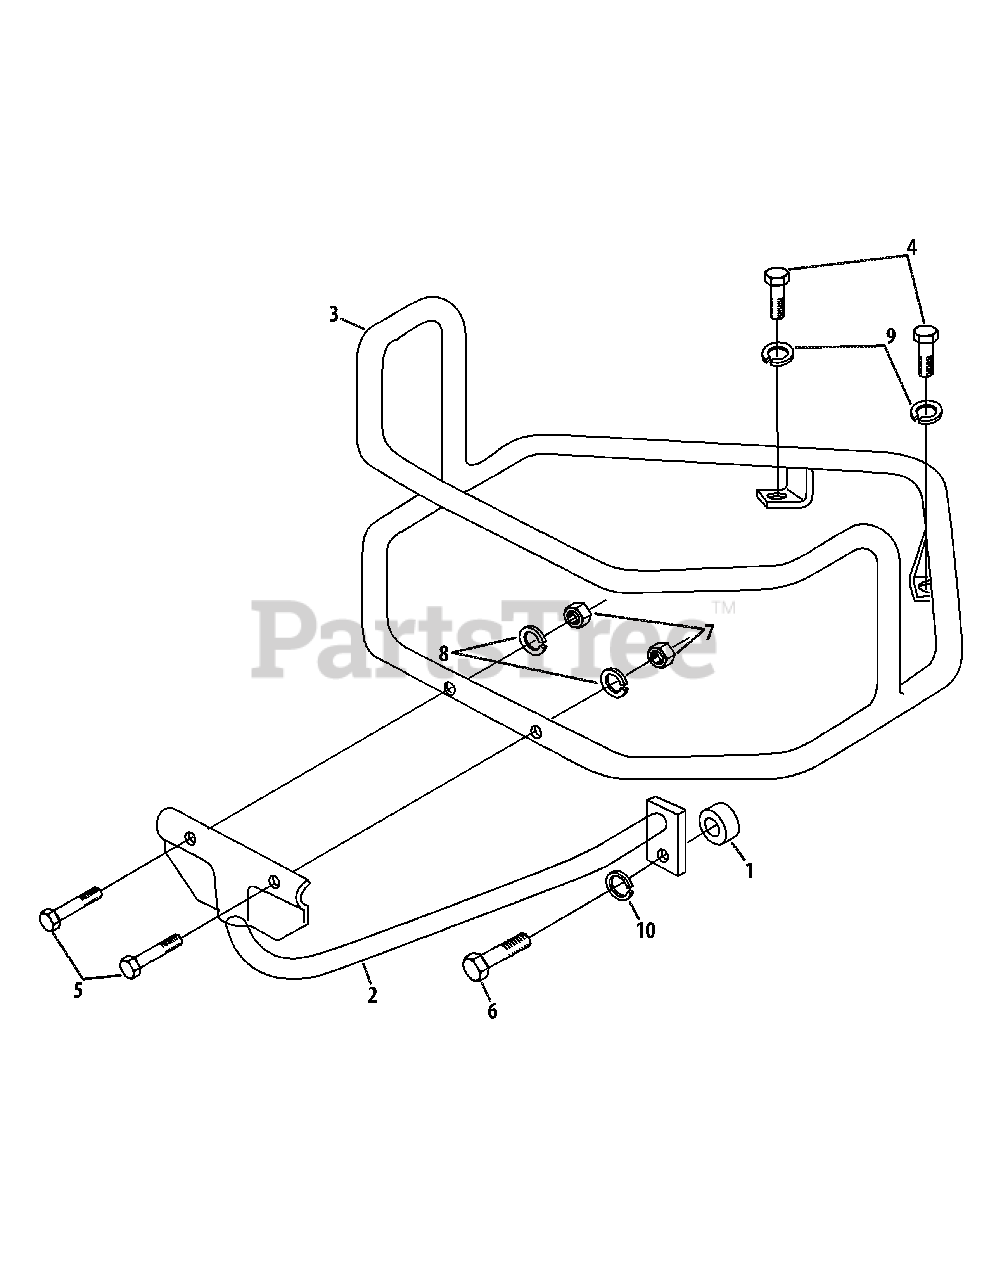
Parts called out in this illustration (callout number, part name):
1	Spacer, 1.0 x .546 x .5
2	Bottom Bumper Brace
3	Bumper Guard
4	Hex Screw, 3/8-16 x 1.00
5	Hex Screw, 5/16-18 x 1.50
6	Hex Screw, 1/2-13 x 1.50
7	Hex Nut, 5/16-18
8	Lock Washer, 5/16
9	Lock Washer, 3/8
10	Lock Washer, 1/2
